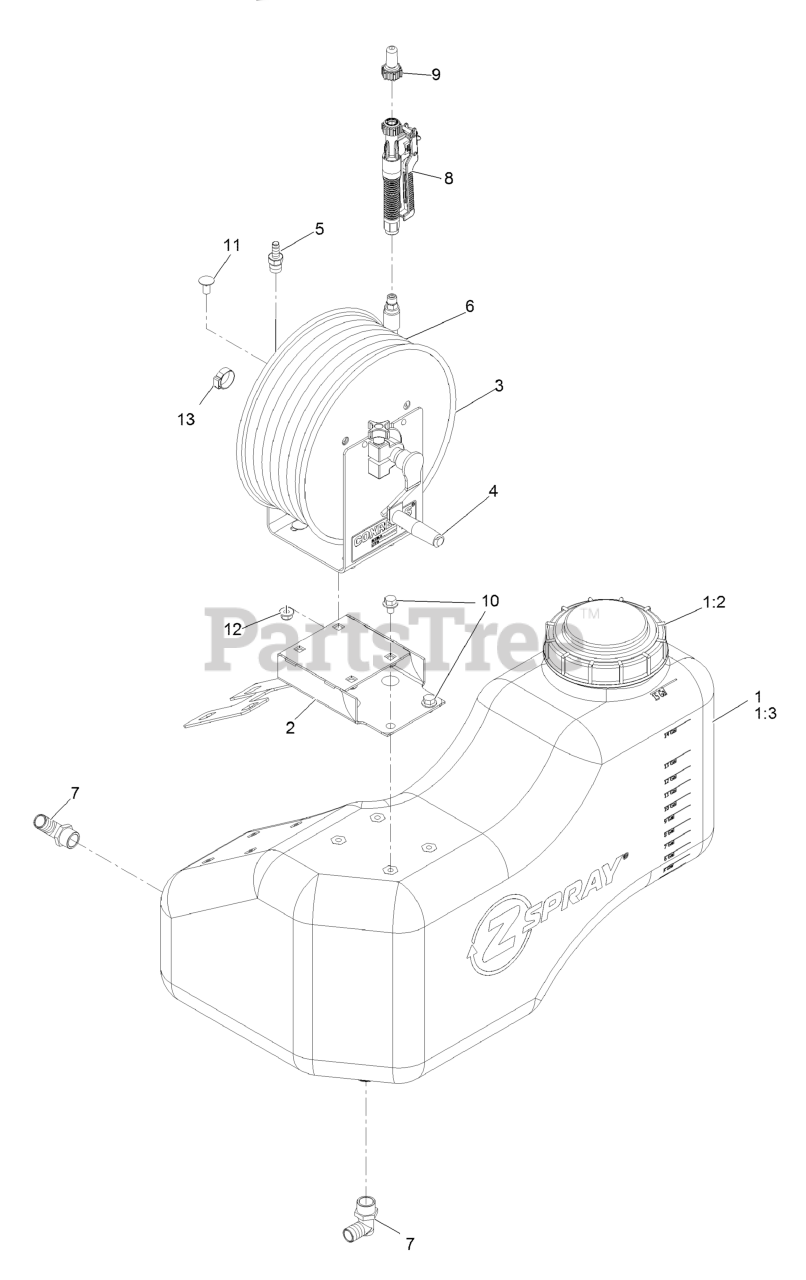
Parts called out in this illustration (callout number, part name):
1	ASM-TANK, LT
1:2	CAP-TANK, SPRAY
1:3	FITTING-BULKHEAD
2	MOUNT-REEL, HOSE
3	REEL-HOSE
4	Crank-Reel
5	FITTING,MALE
6	HOSE-SPRAY, 75'
7	FITTING-ELBOW, 90
8	GUN-SPRAY, SPOT
9	TIP-SPRAY, #12 SPOT
10	Screw-HHF
11	SCREW-CARRIAGE
12	Nut-Hex Flange
13	CLAMP-OETIKER, 167
